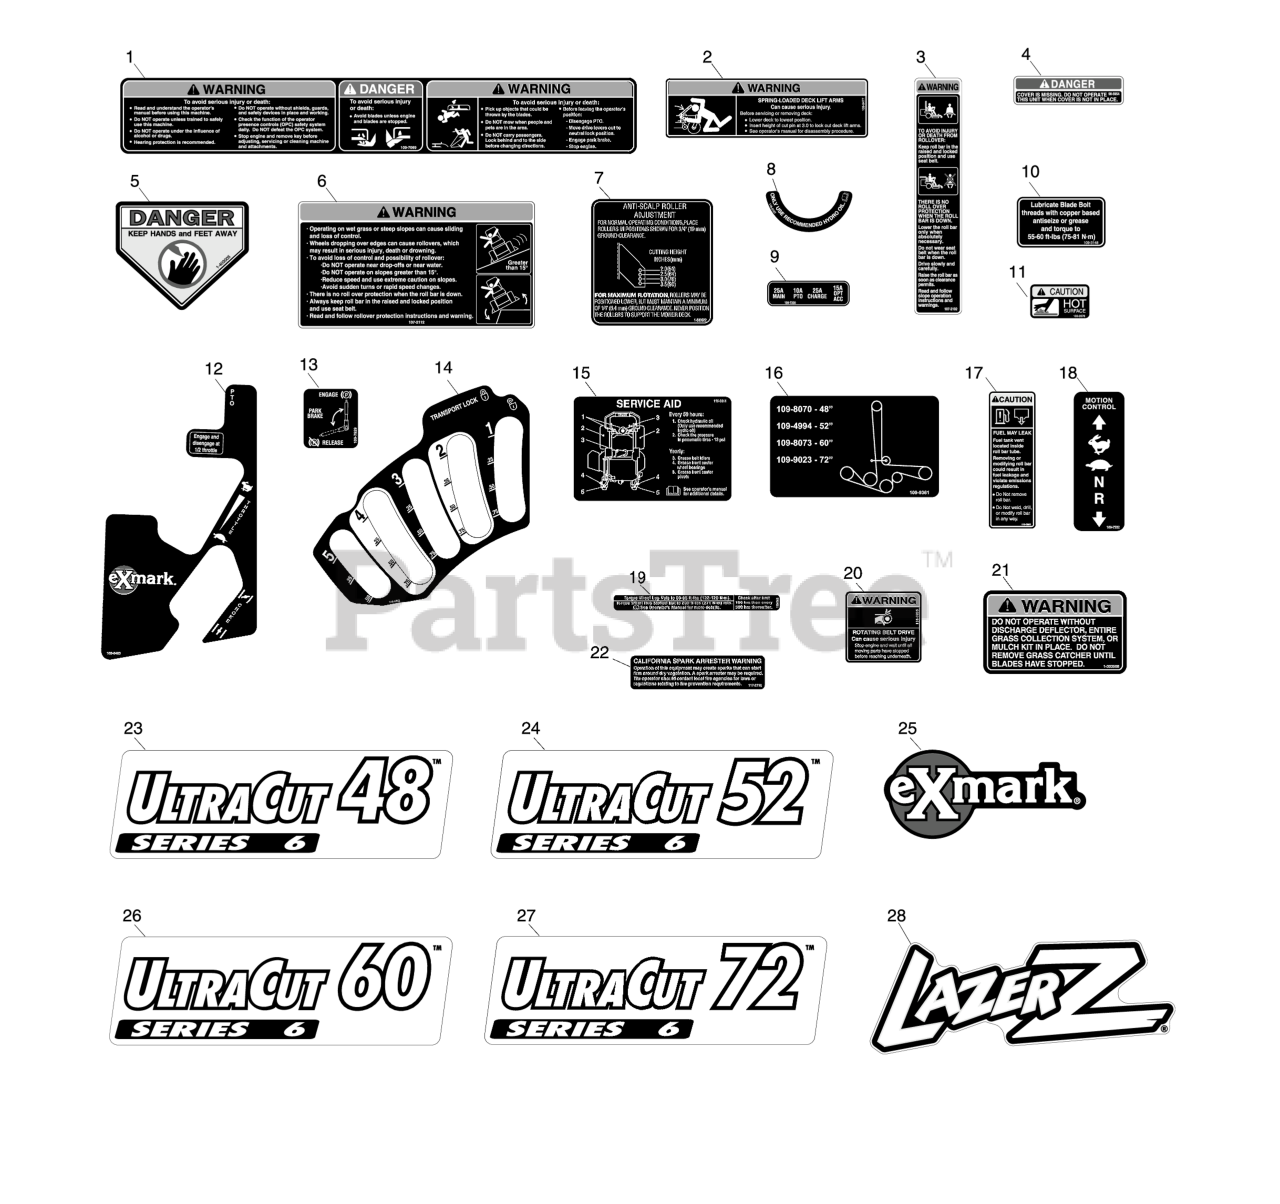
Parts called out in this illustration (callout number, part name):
1	DECAL-CONSOLE
2	DECAL-WARNING
3	DECAL-WARNING, FOLDING RO
4	DECAL-COVER, MISSING
5	DECAL-DANGER
6	DECAL-WARNING
7	DECAL,ANTISCALP
8	DECAL-HYDRO OIL
9	DECAL-FUSE
10	DECAL,BOLT TORQUE
11	DECAL-CAUTION
12	DECAL-CONTROL PANEL
14	DECAL-HOC
15	DECAL-SERVICE AID
16	DECAL,BELT ROUTING
17	DECAL-CAUTION
18	DECAL-MOTION CONTROL
19	DECAL-HUB, WHEEL
20	DECAL-BELT DRIVE
21	DECAL-WARNING, DISCHARGE
22	DECAL-ARRESTER, SPARK
23	DECAL,ULTRACUT 48 SERIES
24	DECAL,ULTRACUT 52 SERIES
26	DECAL,ULTRACUT 60 SERIES
27	DECAL,ULTRACUT 72 SERIES
28	DECAL,LAZER MODEL
